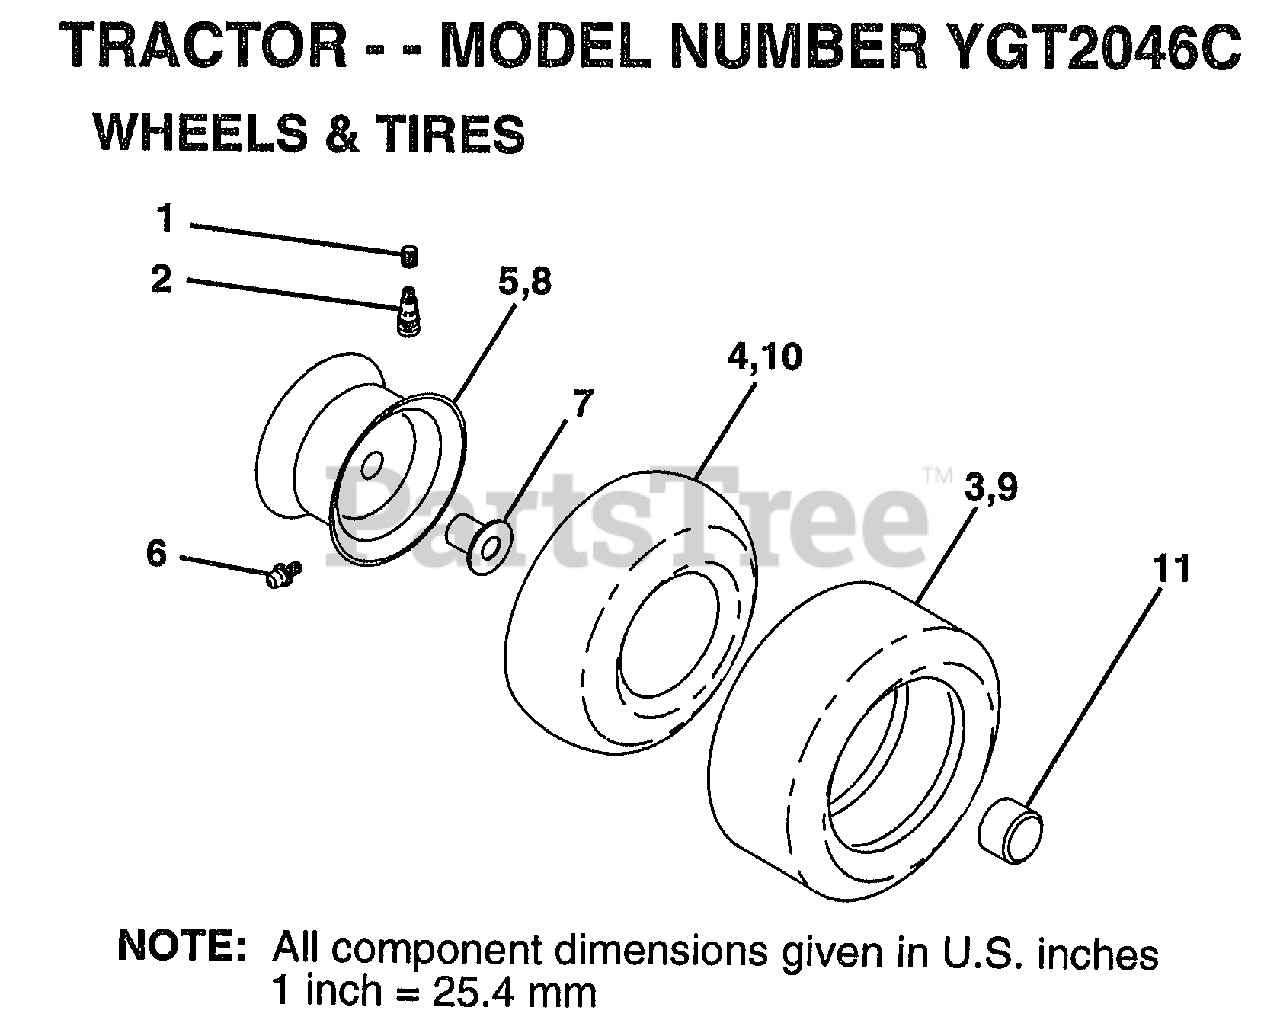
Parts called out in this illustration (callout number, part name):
1	VALVE CAP
2	VALVE STEM LT
4	TUBE.5.3/4.5/6
5	"RIM ASM 8"" FRT"
6	FITTING LT
7	"FLANGE, BEARING"
8	RIM.REAR.
9	TIRE.R.23X9.5-12
10	TUBE.23X8/10-12
11	HUB CAP
